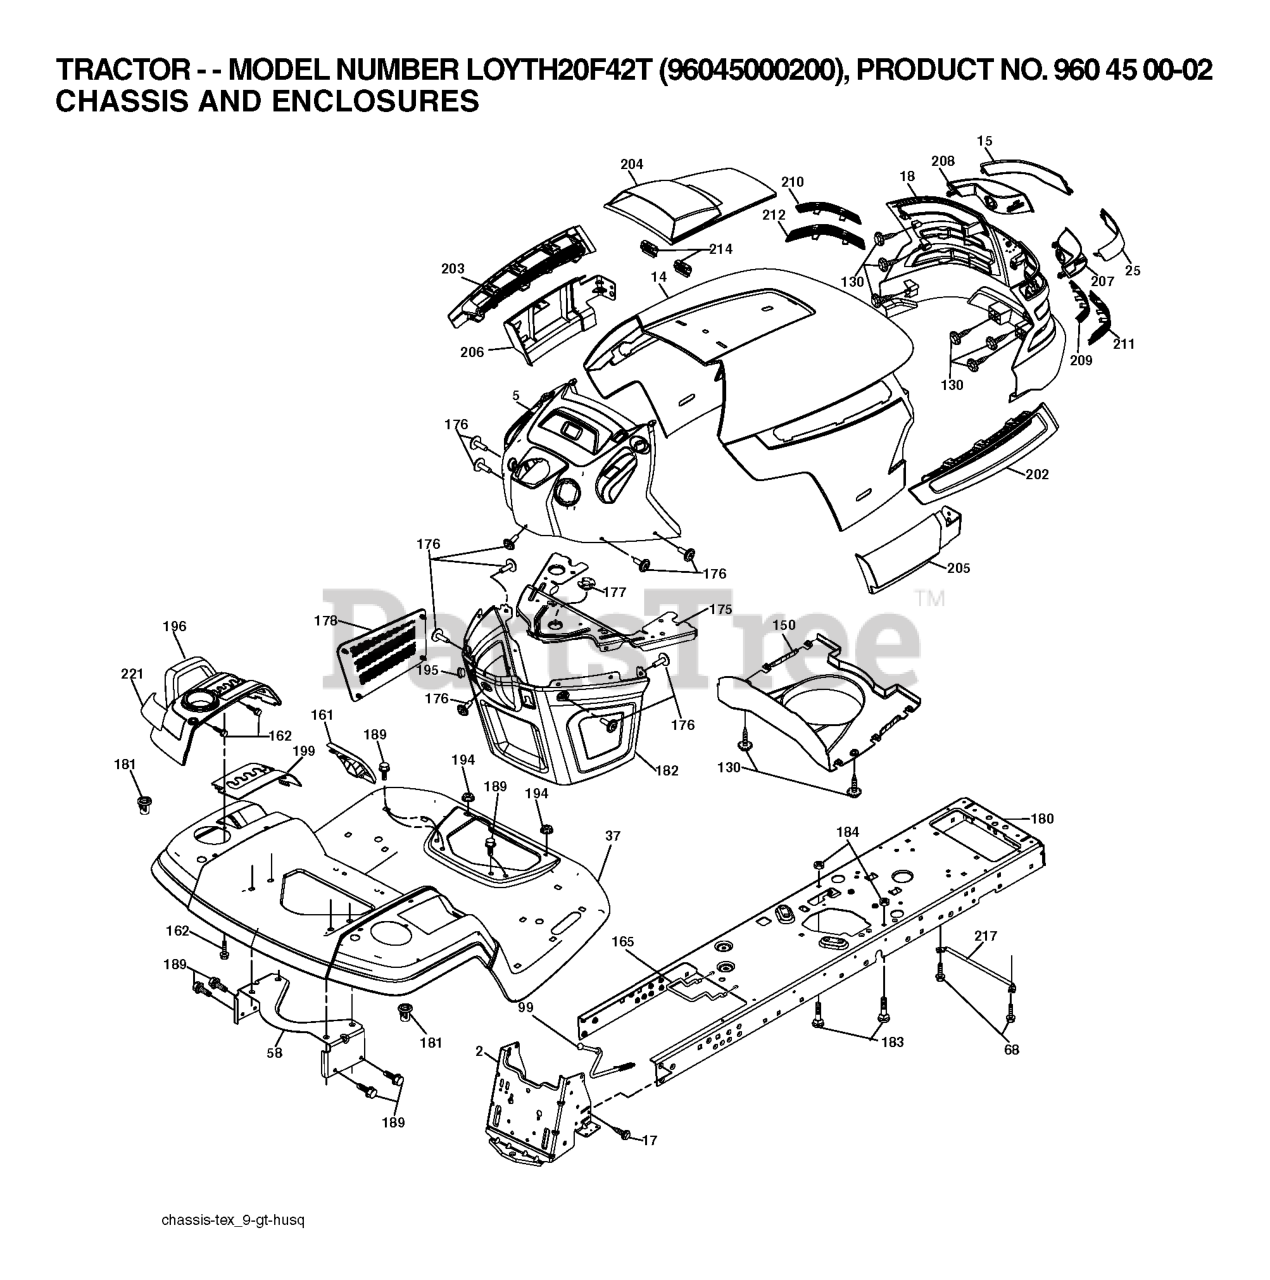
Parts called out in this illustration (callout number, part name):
14	HOOD.PNT.HUSQVARNA.GT.
15	LENS.LH.TEX.GT.HUSQ.CL
17	SCREW 3/8-16X3/4
18	GRILLE.ASM.TEX.GT.HUSQ
25	LENS.RH.TEX.GT.HUSQ.CL
37	FENDER.PNT.TX.GT.CH/FW.ORANGE
58	BRKT.SUPPORT.FNDR/TANK
68	Screw 5/16-18 x 1/2 Hex, Self Tapping 5/16-18 x 1/2
99	ROD.ASM.BYPASS.0610.FE
130	SCREW
150	AIR.DUCT.TEXGT.HUSQ.SV
161	CONSOLE.FUEL.WINDOW.HU
162	SCREW.HI-LO.CONSOLE
175	PLATE.CROSSMEMBER.HUSQ
176	SCREW.#10-24X5/8.RN.QU
177	BUSHING, STEERING
178	CARGO.ASM.NET.TXGT.W/C
180	CHASSIS.STAMPING.LT/GT
181	BUSHING.MNT.FEND.CRGO.
182	DASH.LOWER.COMMON.12V.
183	BOLT.5/16-18X1-1/4 FULL.THREAD
184	SPACER.FENDER
189	SCREW
194	NUT LOCK HEX FLANGE 5/16-18
195	PLUG.12V.ADAPTER.CAPLU
196	RP CONSOLE.ASM.DECKLFT.W/
199	PLATE.DECK.LIFT.HUSQVARNA.GT
202	VENT.SIDE.HOOD.HUSQ.RH.GREY
203	VENT.SIDE.HOOD.HUSQ.LH.GRAY
204	VENT.TOP.HOOD.HUSQVARN
205	SKIRT.HOOD.SIDE.HUSQ.RH.GREY
206	SKIRT.HOOD.SIDE.HUSQ.LH.GREY
207	BEZEL.RH.TEX.GT.HUSQ
208	BEZEL.LH.TEX.GT.HUSQ
209	INSERT.HEX.GRILL.HUSQ.GREY
210	INSERT.HEX.GRILL.HUSQ.
211	INSERT.HEX.GRILL.HUSQ.
212	INSERT.HEX.GRILL.HUSQ.
214	CLIP.RETAINER.TINNER.
217	ROD PIVOT CHASSIS/HOOD
221	REFLECTOR.LH.TEX GT HU
